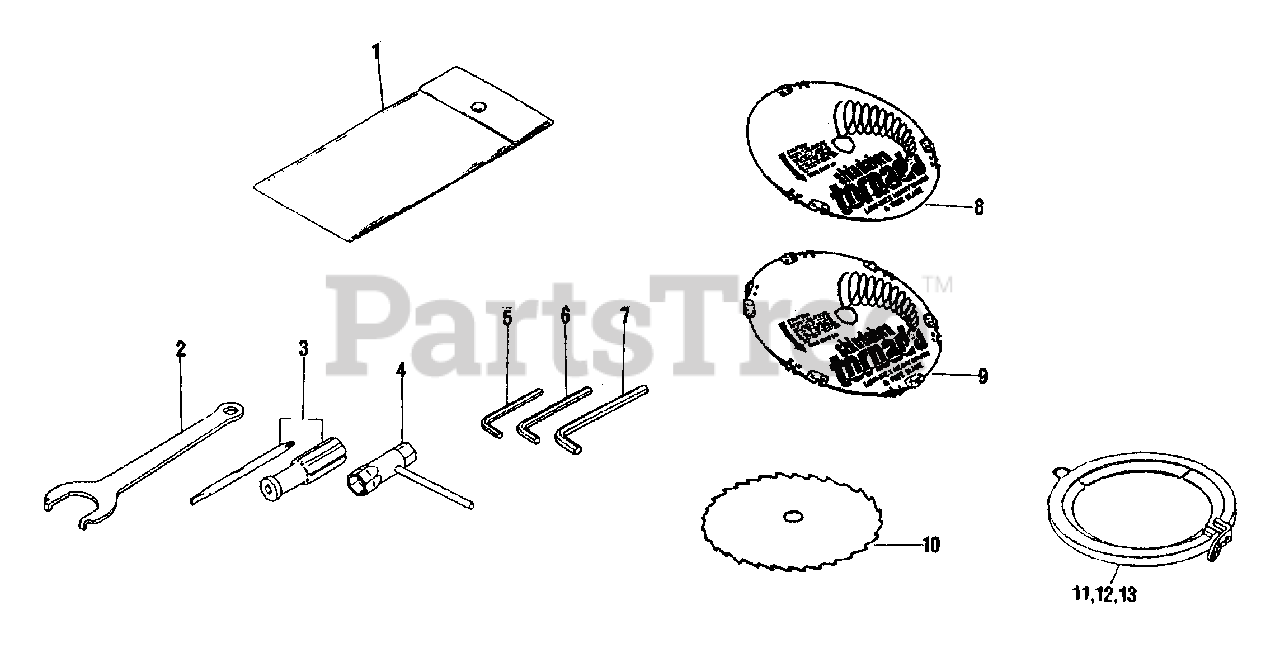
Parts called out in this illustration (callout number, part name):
1	BAG, TOOL
2	SPANNER
3	SCREWDRIVER
4	T-WRENCH - 17X19mm
5	HEX KEY - 3mm
6	HEX KEY - 4mm
7	HEX KEY - 5mm
8	BLADE - 6 TOOTH -- 9" (22cm)
9	BLADE - 12 TOOTH -- 9" (22cm)
10	BLADE - 30 TOOTH -- 9" (22cm)
11	COVER, BLADE - 8" (20cm)
12	COVER, BLADE - 9" (22cm)
13	COVER - 10"
